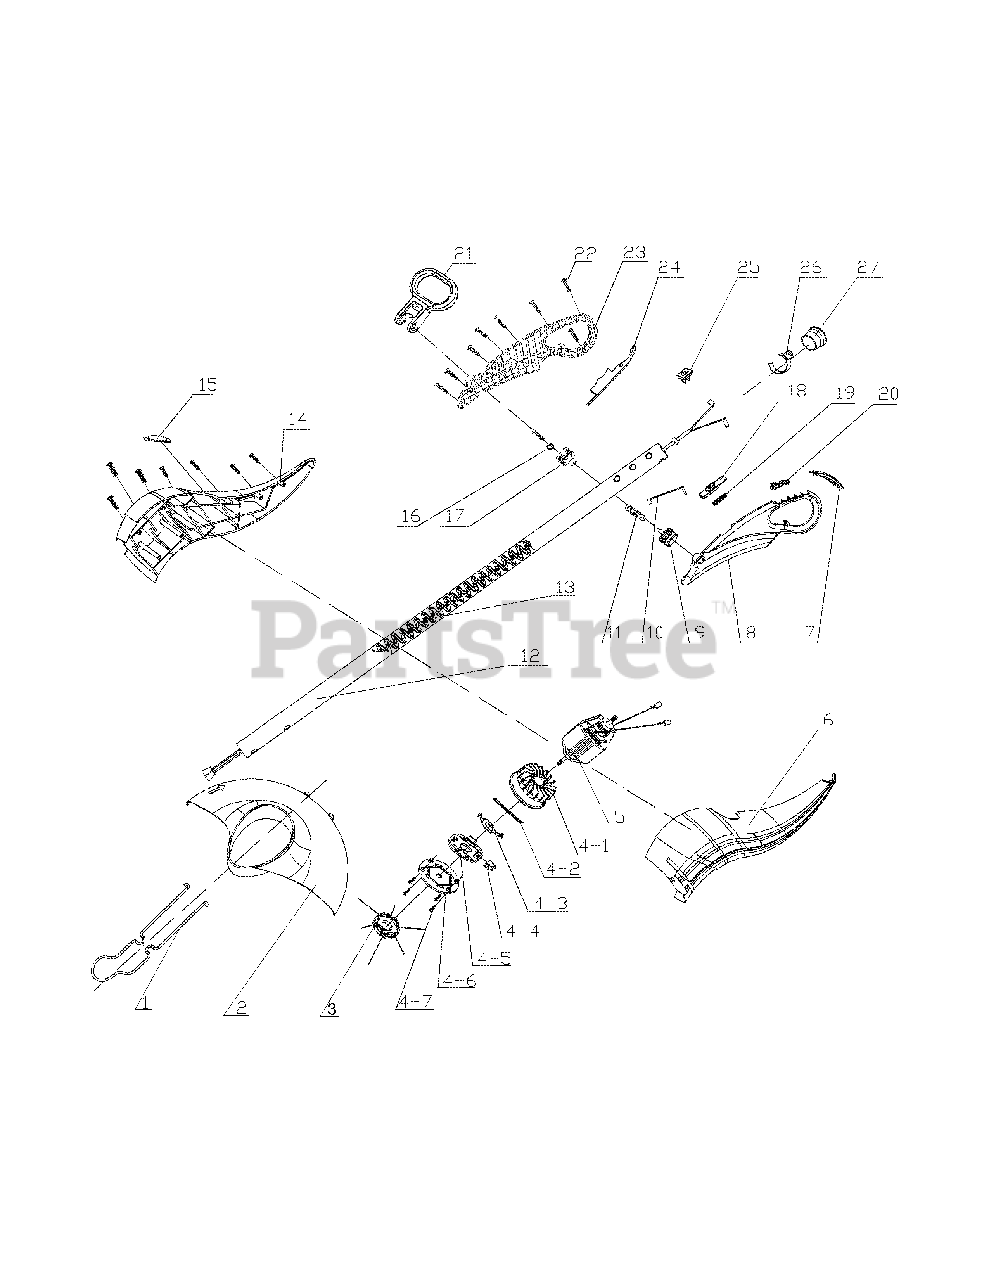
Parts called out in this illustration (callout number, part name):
3	HEAD ASS'Y
4	CUTTING LINE ASS'Y
4-4	PUSH BUTTON
4-5	REX HEAD CEAT
4-6	REX HEAD PLATE
6	HOUSING (L)
8	HANDLE (L)
9	BUTTON (L)
13	SPIRAL WIRE
14	HOUSING (R)
15	HOUSING COVER
17	BUTTON (R)
21	HANDLE ASS'Y
23	HANDLE (R)
25	SLIED SWITCH
26	SNAP BUTTON
27	TUBE GROMMET
